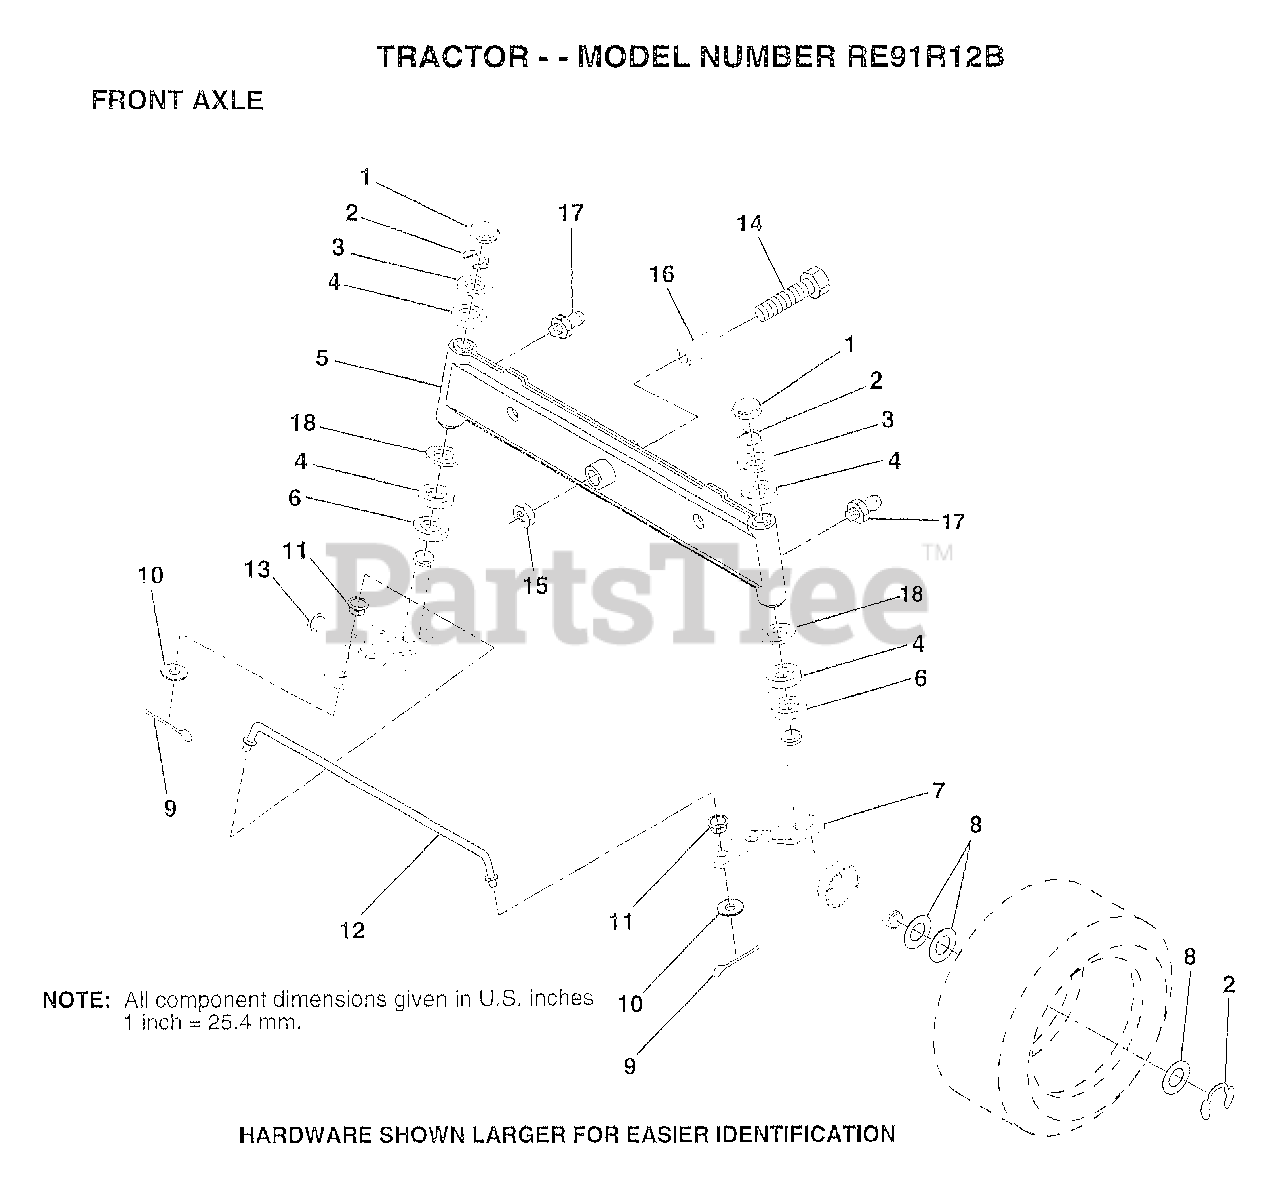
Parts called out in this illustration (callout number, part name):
1	CAP
2	RING
3	WASHER
4	COL. SRTG. BEAR.
5	AXLE ASM FRONT
6	WASHER .T
7	SPINDLE.ASSY.RH
8	WASHER
9	COTTER PIN
10	WASHER
11	BUSHING.DRAGLINK
12	TIE ROD
13	SPINDLE.ASSY.LH
14	BOLT HEX 5/8-11
15	"NUT-LOC,FLANGE LT"
16	BEARING
17	ZERK M
18	WASHER
